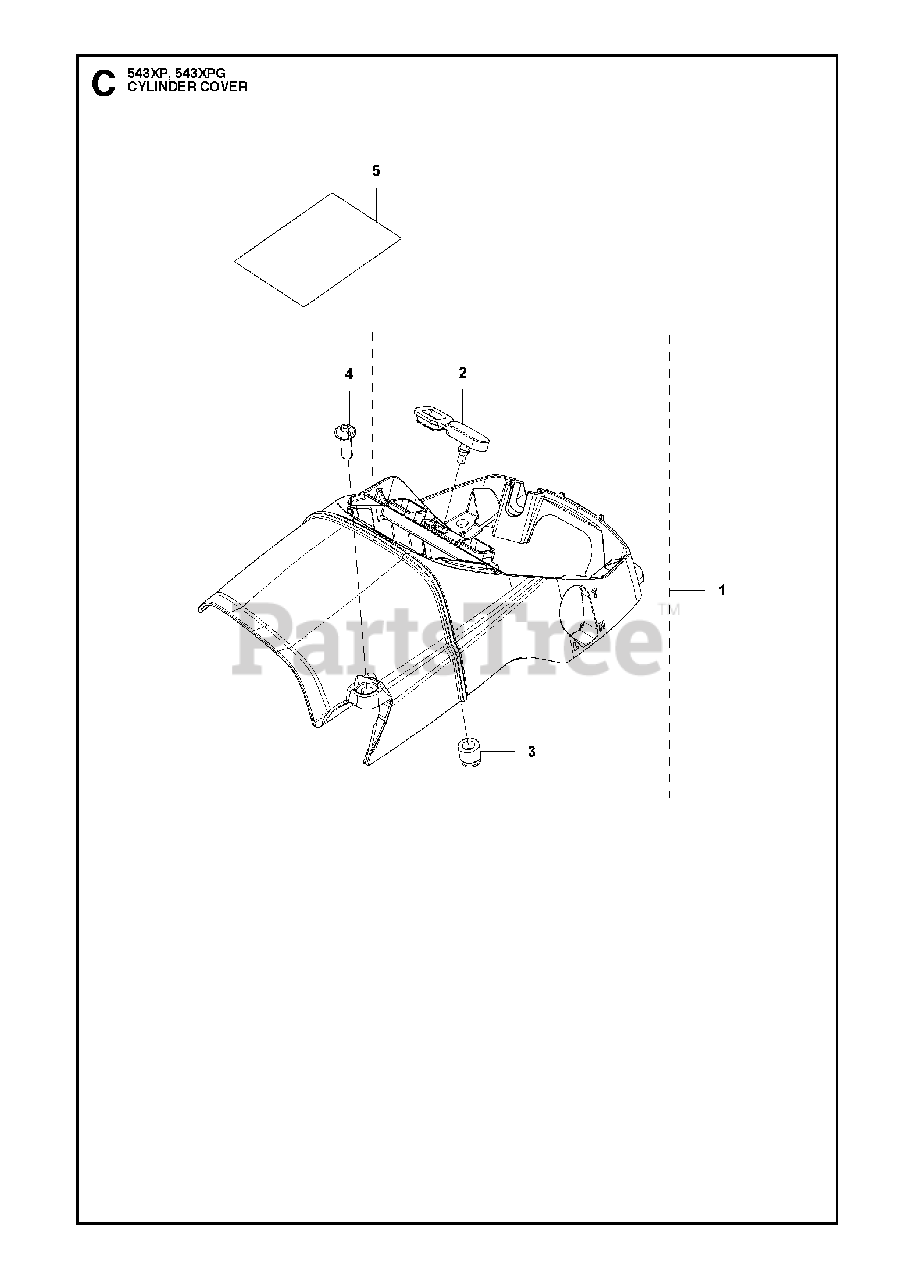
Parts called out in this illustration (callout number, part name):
1	CYLINDER COVER ASSY
2	GROMMET
3	GROMMET
4	SCREW M5 X 14
